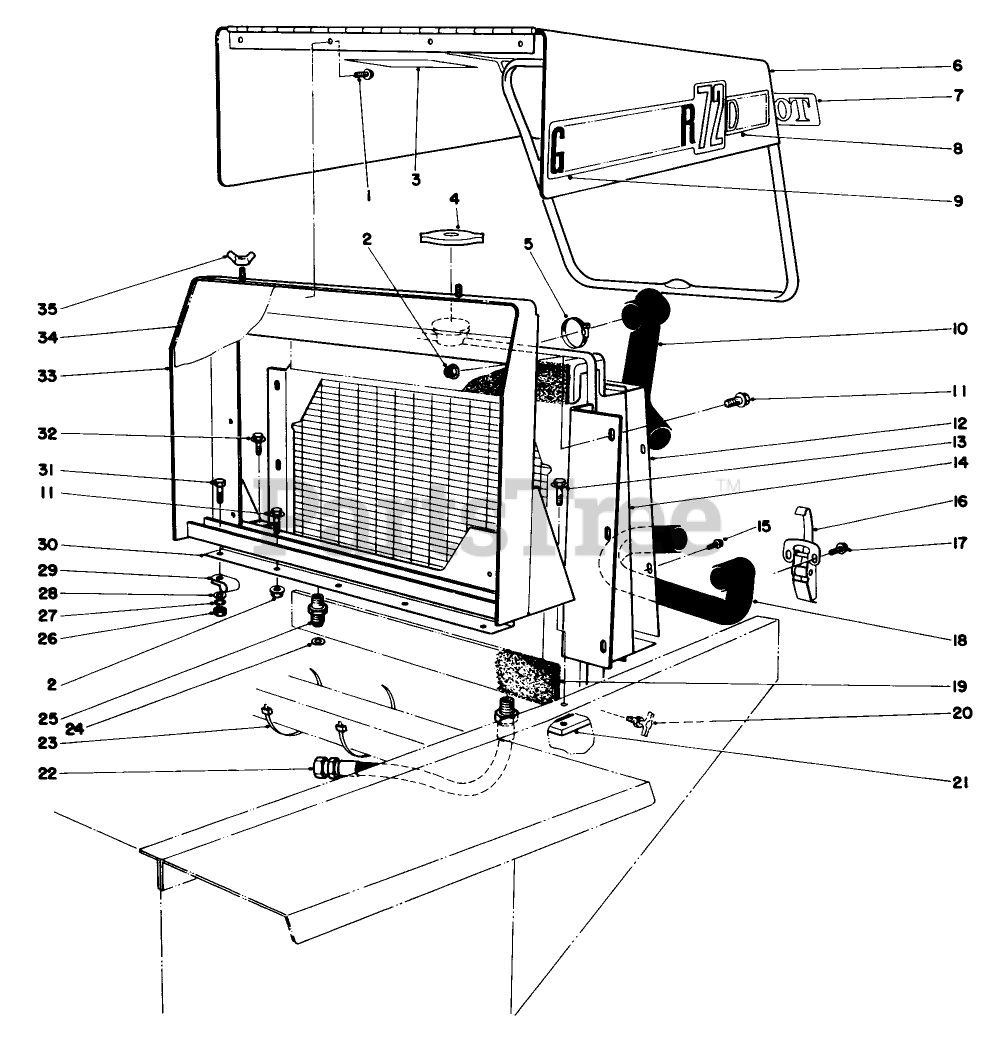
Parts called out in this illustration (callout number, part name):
1	SCREW-HWH
2	NUT-HF
3	Decal
4	RAD PRESS CAP ASM
5	CLAMP-HOSE
7	Decal Toro
8	Decal-Diesel
9	GM-72 DECAL
10	UPPER RADIATOR HOSE
11	SCREW-HHF
12	Radiator Shroud
13	SCREW-HHF
14	RADIATOR SUPT WA R
15	SCREW-THD FRM,HWH
16	CLAMP-SLOTTED
17	10-24 X 1/2 SEMS SCR
18	LOWER RADIATOR HOSE
19	FOAM-RADIATOR
20	DRAINCOCK
21	LH FRAME BAR
22	COOLER TO PUMP HOSE
23	TIE-CABLE
24	WASHER SPECIAL
25	HYD TUBE FITTING
26	NUT-HEX
27	WASHER-LOCK
28	WASHER-PLAIN
29	CLAMP-R
30	Grille-Sealing Plate
31	SCREW-HH
32	SCREW-HWHTF
33	RADIATOR ASM
34	Grille
35	NUT-WING
